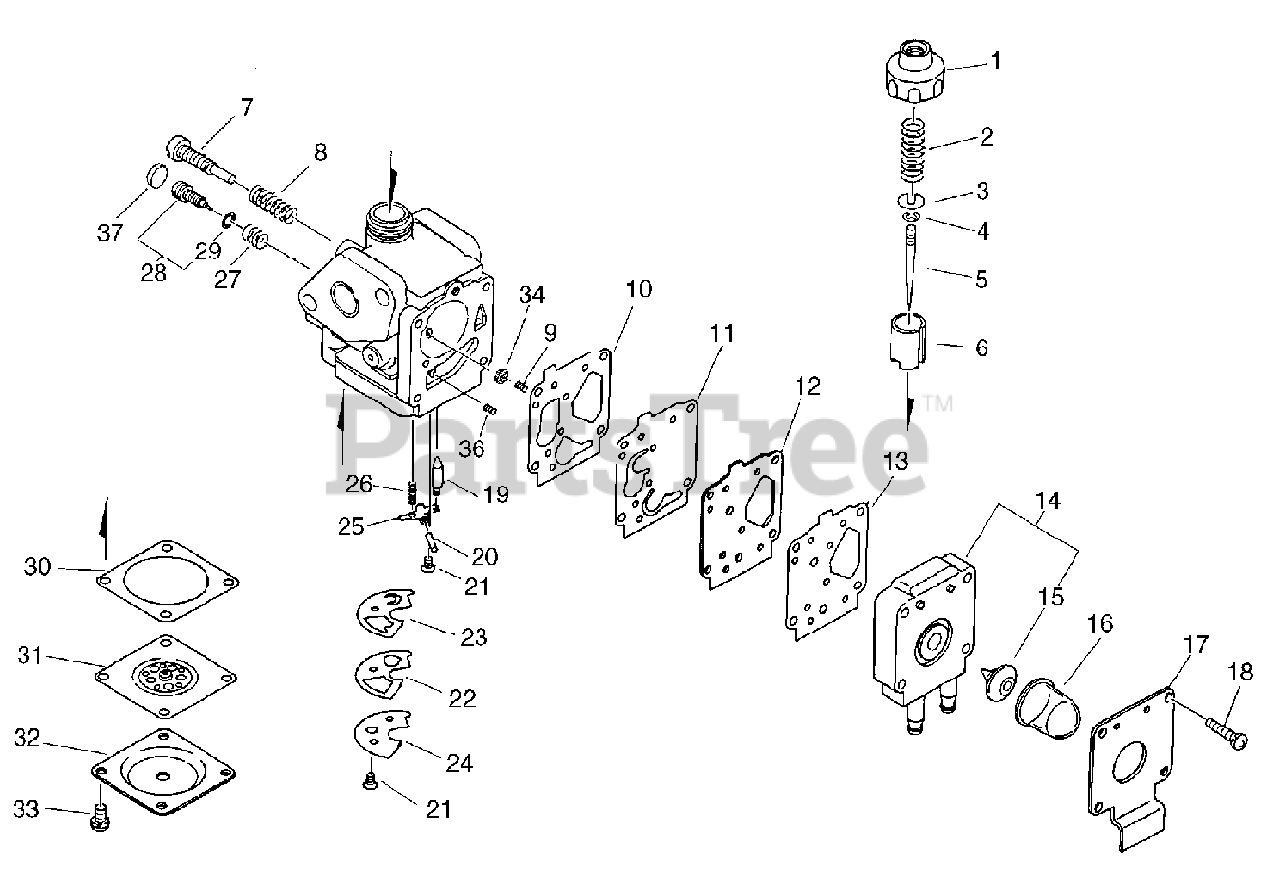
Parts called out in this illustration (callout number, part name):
1	COVER, TOP
2	SPRING, THROTTLE
3	WASHER, SPRING SUPPORT
5	NEEDLE, JET
6	VALVE, THROTTLE
7	SCREW, IDLE ADJUST
9	SPRING
10	GASKET, FUEL PUMP
11	DIAPHRAGM, FUEL PUMP
12	PLATE, FUEL PUMP
13	GASKET, FUEL PUMP
14	COVER ASSY, PUMP
16	BULB, PURGE
17	COVER, PUMP
18	SCREW 3×14
19	VALVE, NEEDLE
20	PIN, METERING LEVER
21	SCREW - 3×8
22	VALVE, CHECK
25	LEVER, INLET CONTROL
28	SCREW, MAIN ADJUST
30	GASKET, DIAPHRAGM
30	GASKET
31	DIAPHRAGM
32	COVER, DIAPHRAGM
33	SCREW 3×8
34	SCREEN, FUEL INLET
36	SPRING, COIL
37	PLATE
